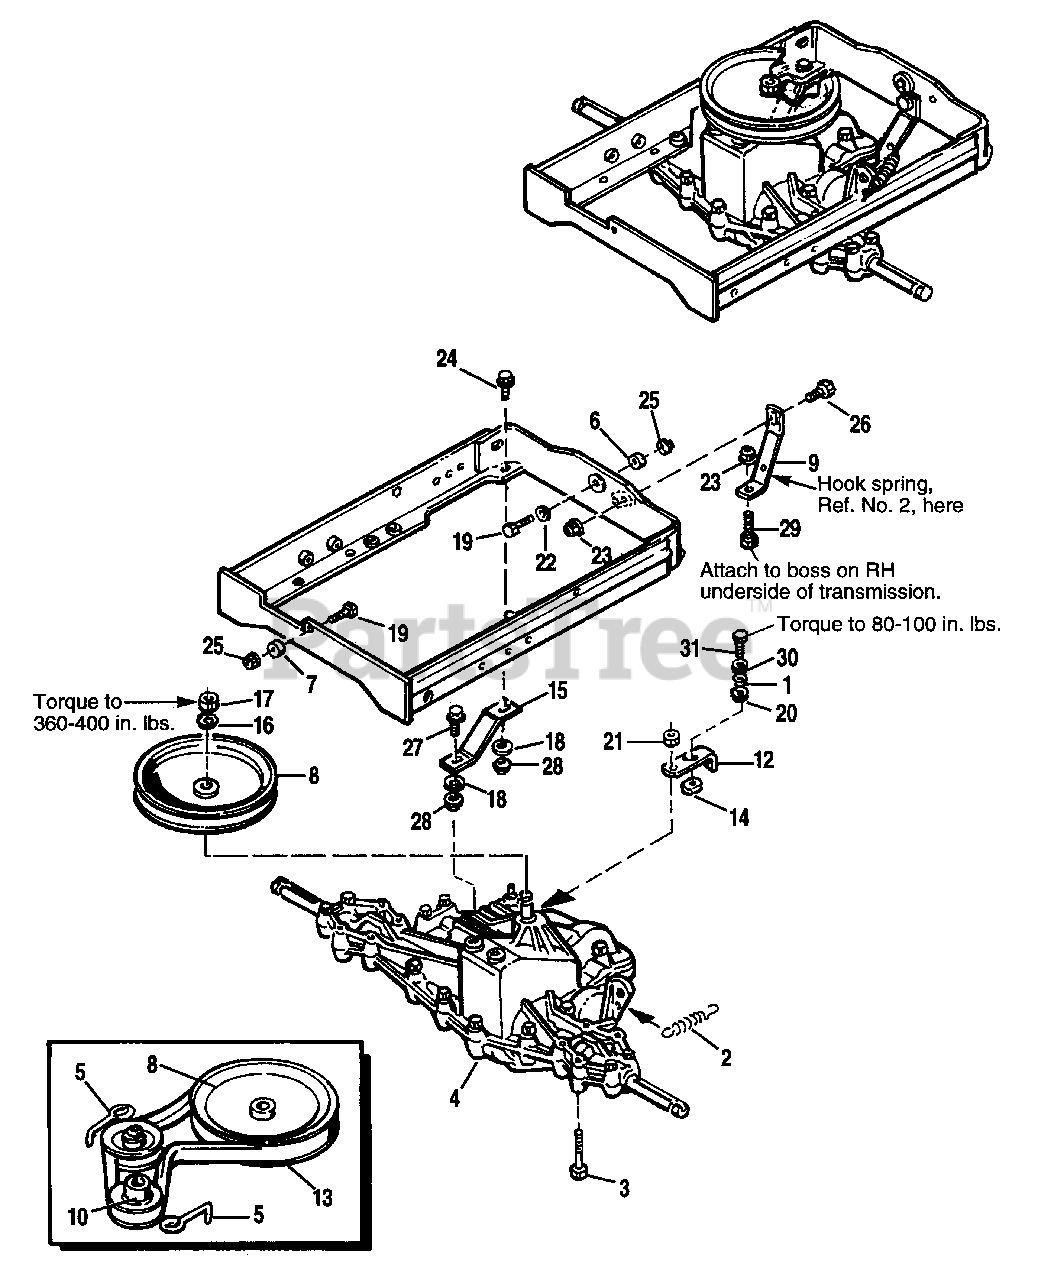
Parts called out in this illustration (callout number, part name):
2	SPRING, Return
3	SCREW, Taptite, 5/16-18 x 2-1/4
4	TRANSMISSION, Hydro
6	BUSHING, Rear
7	BUSHING, Front
8	PULLEY, Transmission
9	STRAP, Torque
10	PULLEY, Engine
11	CARRIER ASSY.
12	LEVER, Release
15	STRAP, Torque
16	LOCKWASHER, 1/2
17	NUT, Hex, Jam, 1/2-20
18	WASHER, 5/16
19	CAPSCREW, Hex Hd., 1/2-13 x 1-1/4
20	WASHER, Plain, 13/32 x 1-1/4 x 1/16
21	NUT, Hex, Lock, 1/4-20
22	WASHER, Plain, 17/32 x 1-1/4 x 5/64
23	NUT, Hex, Flange Whiz, 5/16-18
24	SCREW, Hex, Whizlock, 5/16-18 x 3/4
25	NUT, Hex, Flange Lock, 1/2 x 13
26	CARRIAGE BOLT, 5/16-18 x 5/8
27	SCREW, Hex, Whizlock, 5/16-18 x 1-1/2
28	NUT, Flange, 2-Way Lock, 5/16-18
29	CAPSCREW, Hex, 5/16-18 x 2-1/4
30	WASHER, Plain, 1/4 x 1-1/4 x 5/64
31	SCREW, Taptite, #10-24 x 1-1/4
